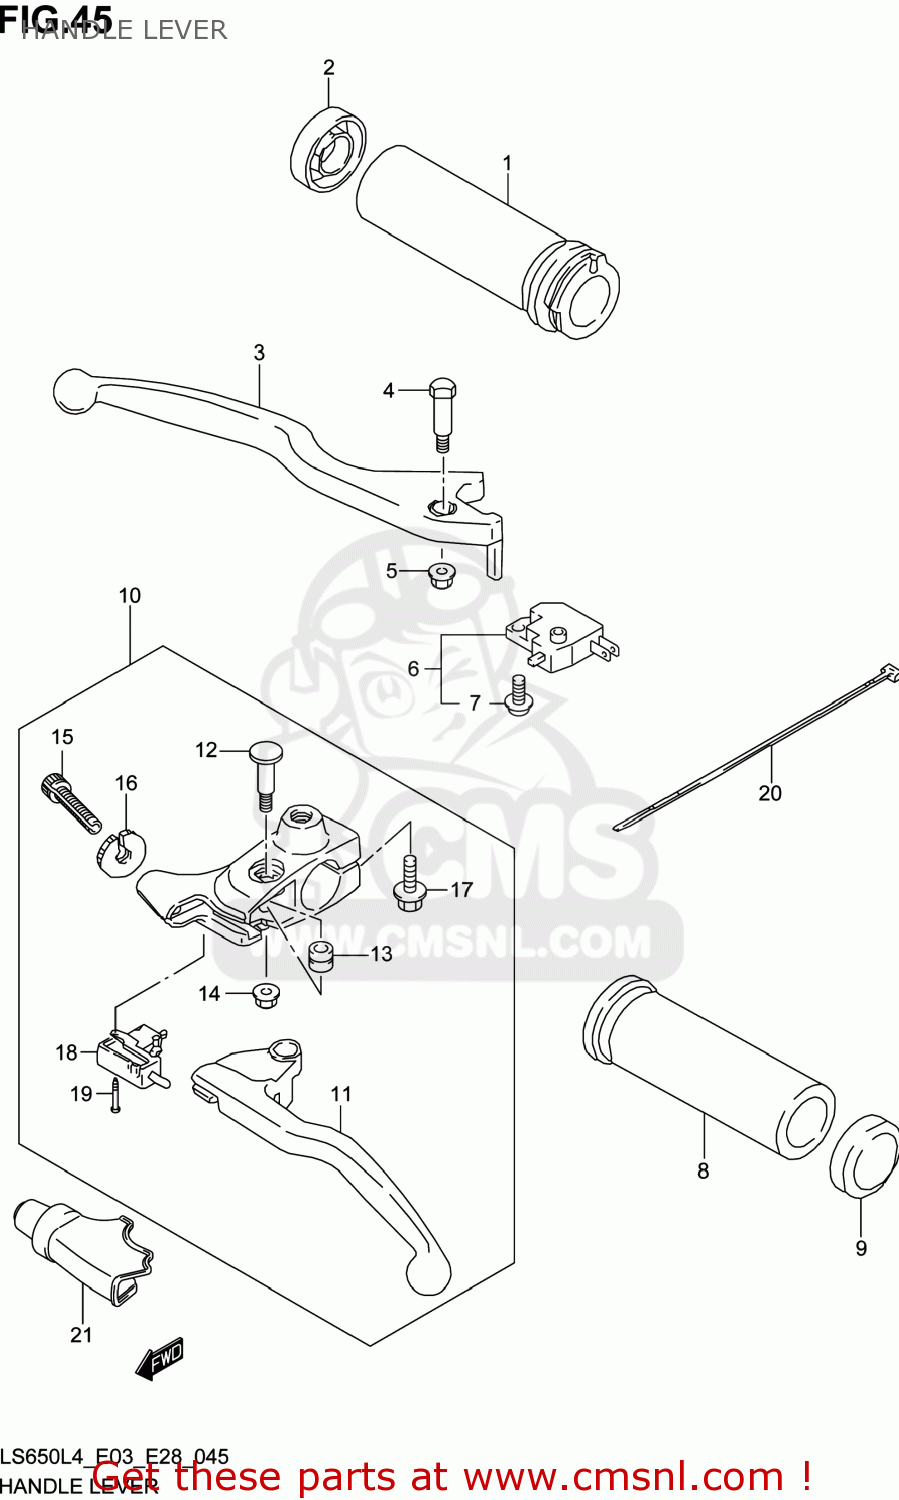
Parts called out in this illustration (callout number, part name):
1	GRIP,THROTTLE
2	CAP,GRIP END
3	LEVER,BRAKE
4	BOLT,LEVER SET
5	NUT
6	SWITCH ASSY,FR BRAKE
7	SCREW
8	GRIP,L
9	CAP,GRIP END
10	LEVER ASSY,CLUTCH
11	LEVER,CLUTCH
12	BOLT,CLUTCH LEVER
13	SPACER,CLUTCH LEVER PIVOT
14	NUT
15	ADJUSTER,WIRE
16	NUT,LOCK
17	BOLT
18	SWITCH,CLUTCH
19	SCREW
20	CLAMP(L:250)
21	COVER,CLUTCH LEVER
